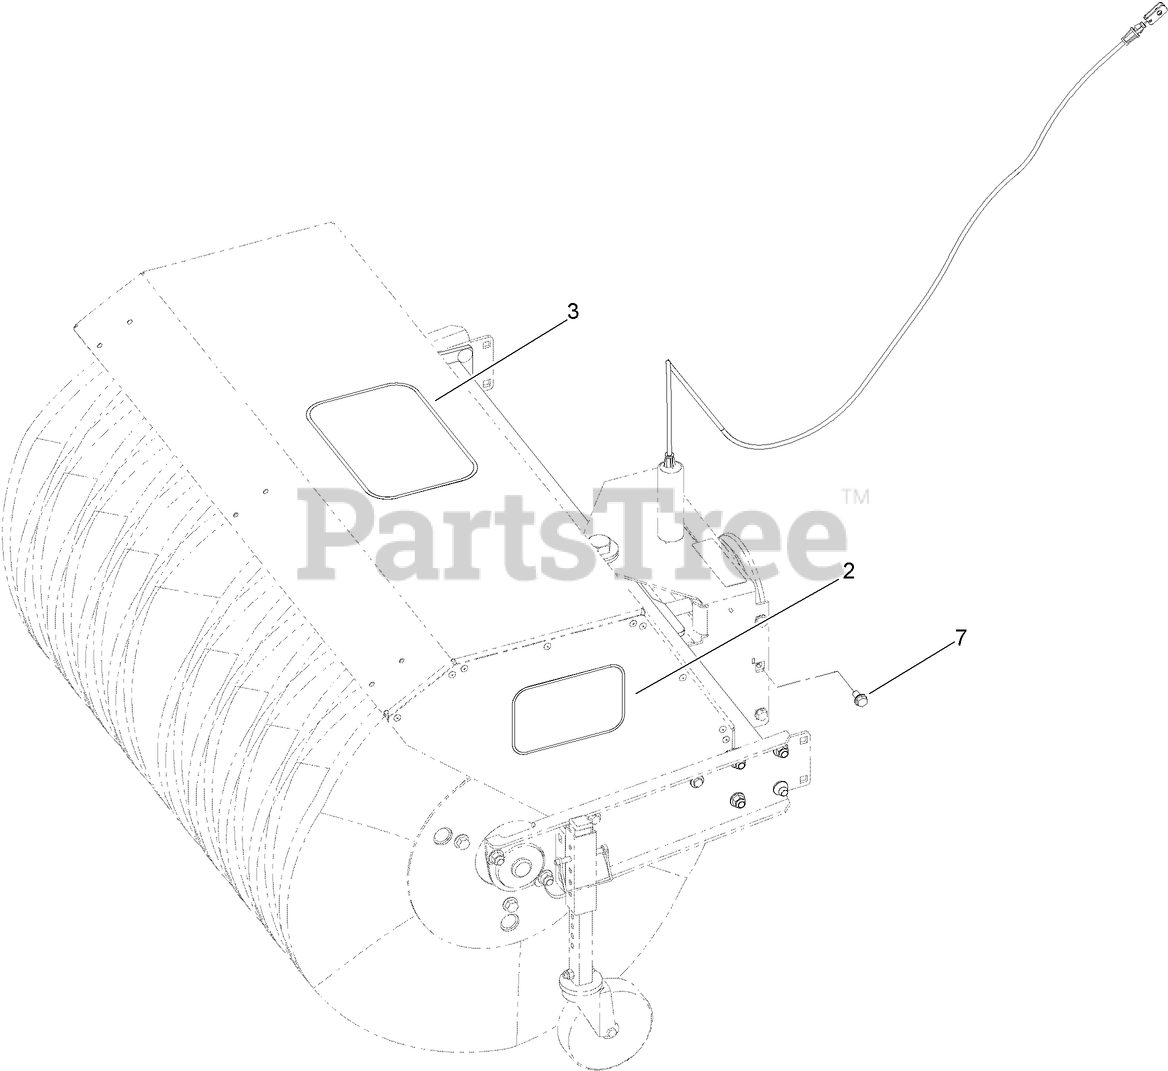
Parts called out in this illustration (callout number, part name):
2	DECAL
3	DECAL
7	SCREW-HWHTF
